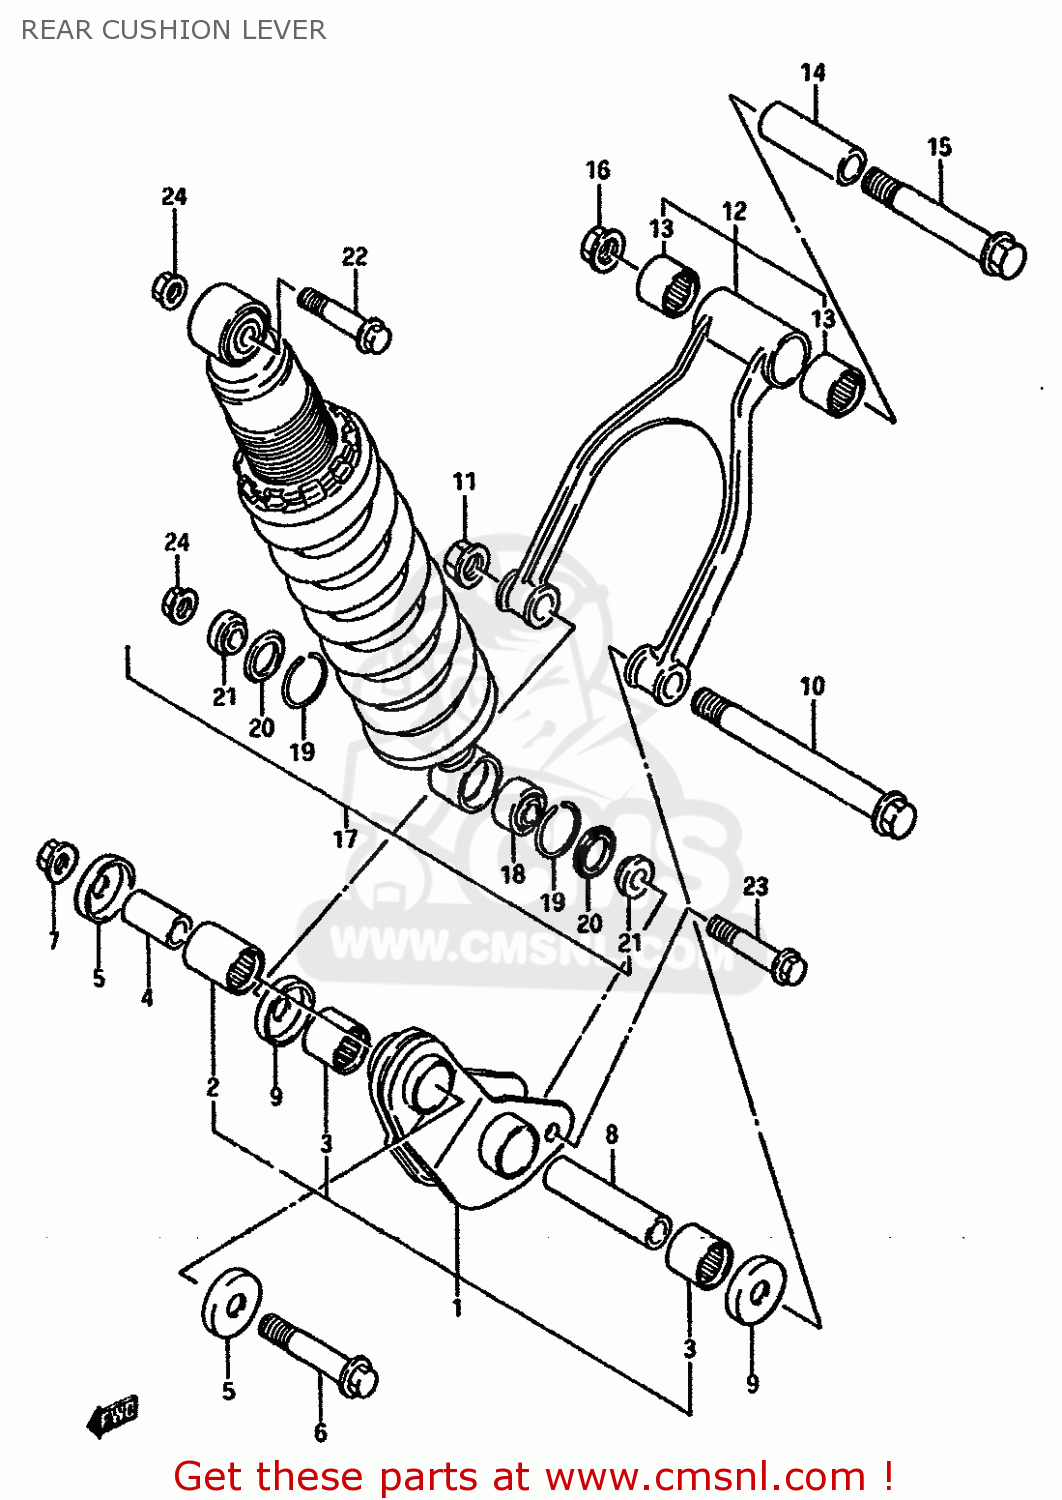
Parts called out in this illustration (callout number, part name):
1	LEVER SET, REAR CUSHION
2	BEARING(20X27X30)
3	BEARING(20X27X23.5)
4	SPACER,RR CUSHION LEVER FR
5	SEAL,RR CUSHION LEVER FR DUST
6	BOLT,RR CUSHION LEVER FR
7	NUT 12MM
8	SPACER (14X20X78)
9	SEAL,RR CUSHION LEVER CTR DUST
10	BOLT,RR CUSHION ROD LWR
11	NUT
12	LEVER SET,REAR CUSHION
13	BEARING(20X27X23.5)
14	SPACER (14X20X63)
15	BOLT,RR CUSHION ROD UPR
16	NUT
17	ABSORBER ASSY,REAR SHOCK (WHITE)
18	BEARING,REAR SHOCK ABSORBER
19	RING
20	SEAL,DUST RR SHOCK ABSORBER
21	COLLAR
22	BOLT(10X50)
23	BOLT(10X54)
24	NUT
